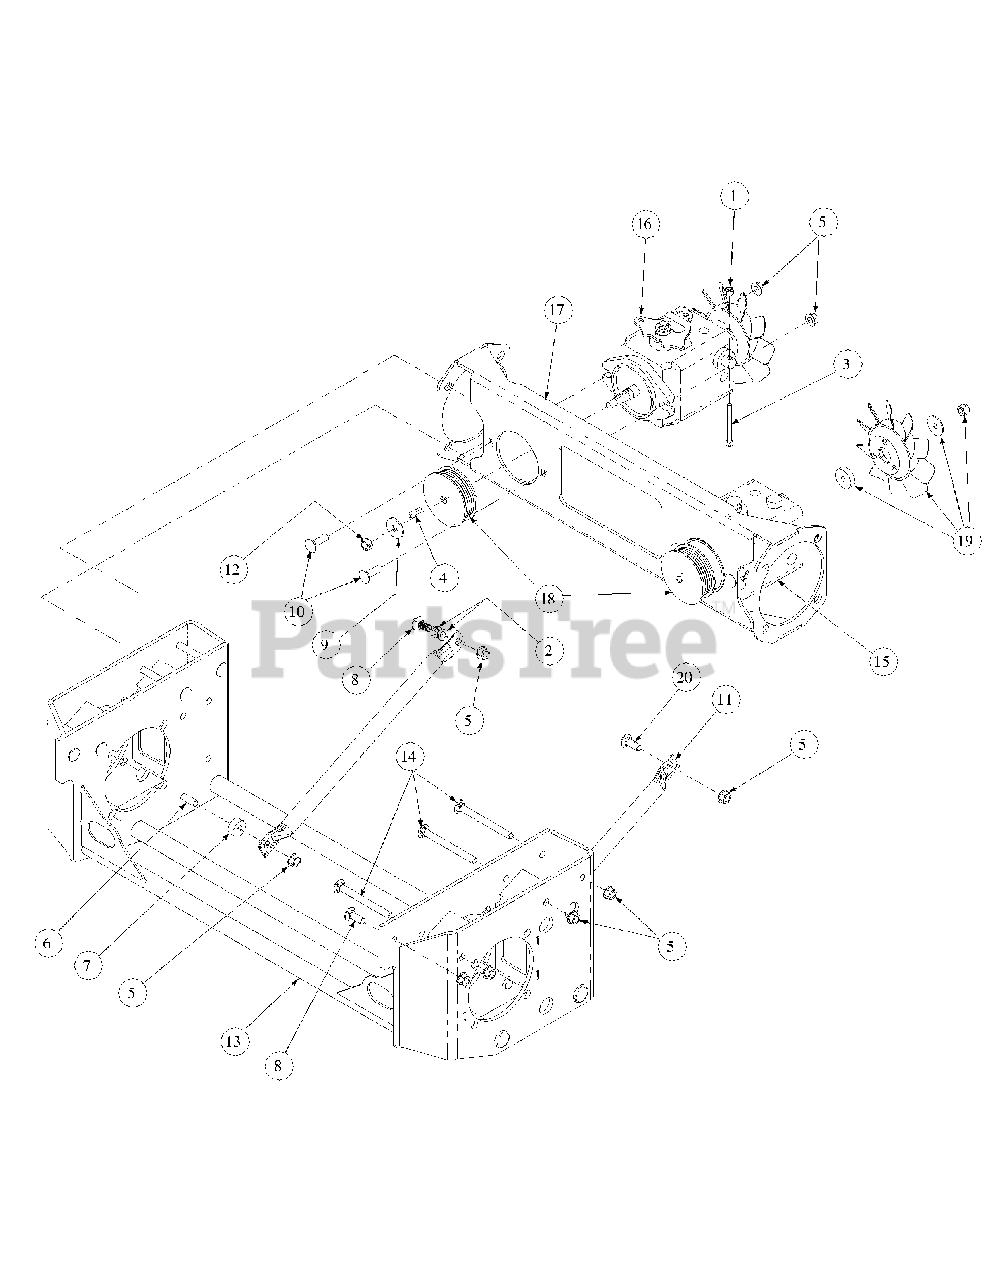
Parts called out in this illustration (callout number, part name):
1	Lock Nut, Nylon Insert, 1/4-20
2	Washer lock 3/8 zinc
3	Hex Cap Screw, 1/4-20 x 2.00
4	Key, 3/16" x 7/8"
5	Flange Lock Hex Nut, 3/8-16
6	Hex Cap Screw, 2/8 -16 x 1.25
7	Spacer, .406 ID x 1.00 OD x .38
8	Carriage Bolt, 3/8-16 x 1
9	Flat Washer, 3/8
10	Carriage Screw, 3/8-16 x 1.25
12	Hex Nut, 3/8-24
13	Hydro Motor Frame Assembly
14	Carriage Bolt, 3/8-16 x 4.00
15	Hydro Pump, RH
16	Hydro Pump, LH
17	Hydro Pump Mounting Weldment
18	Hydro Pulley Pump
19	Kit, Fan BDP
20	Carriage Bolt, 3/8-16 x .75
